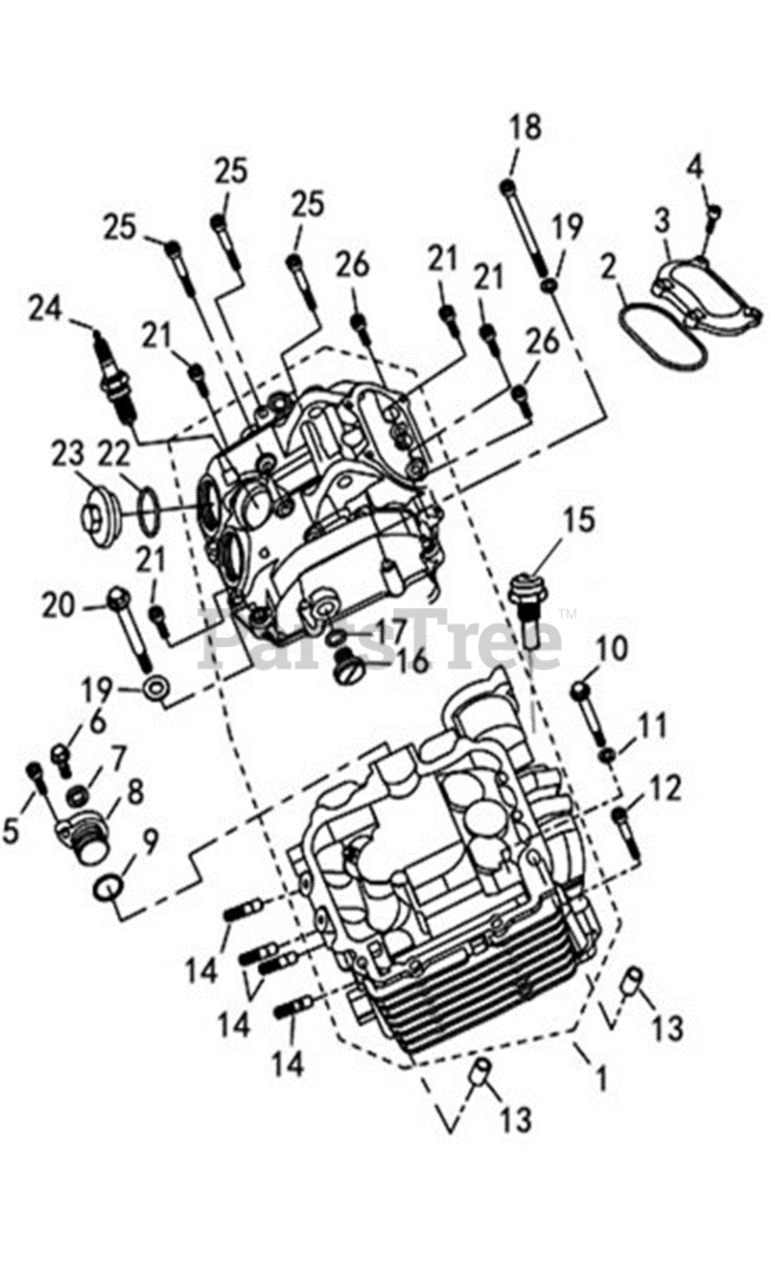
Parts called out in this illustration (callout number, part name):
1	Cylinder Head Bare
2	O-Ring 71.5X3
3	Cover,Intake Valve
4	Hexagon socket head cap screws M6X20
5	Hexagon socket head cap screws M6X20
6	Hexagon flange bolts M6X12
7	Aluminum Washer 6X12X1.5
8	Camshaft End Cover
9	O-Ring 18.7X2.45
10	Cylinder bolts M9X109
11	Washer 10X19X2
12	Hexagon socket head cap screws M6X50
13	Pin,Dowel 10X16
14	Double-headed bolt M8X45(SUS)
15	Water Temperature Sensor
16	Peep Hole Cover
17	O-Ring 13.4X2.35
18	Hexagon socket head cap screws M6X130
19	Aluminum Washer 6X12X2
20	Hexagon socket head cap screws M6X115
21	Hexagon socket head cap screws M6X25
22	O-Ring 32.7X3.1
23	Cover,Exhaust Valve
24	Spark Plug NGK DCPR7E
25	Hexagon socket head cap screws M6X55
26	Hexagon socket head cap screws M6X40
